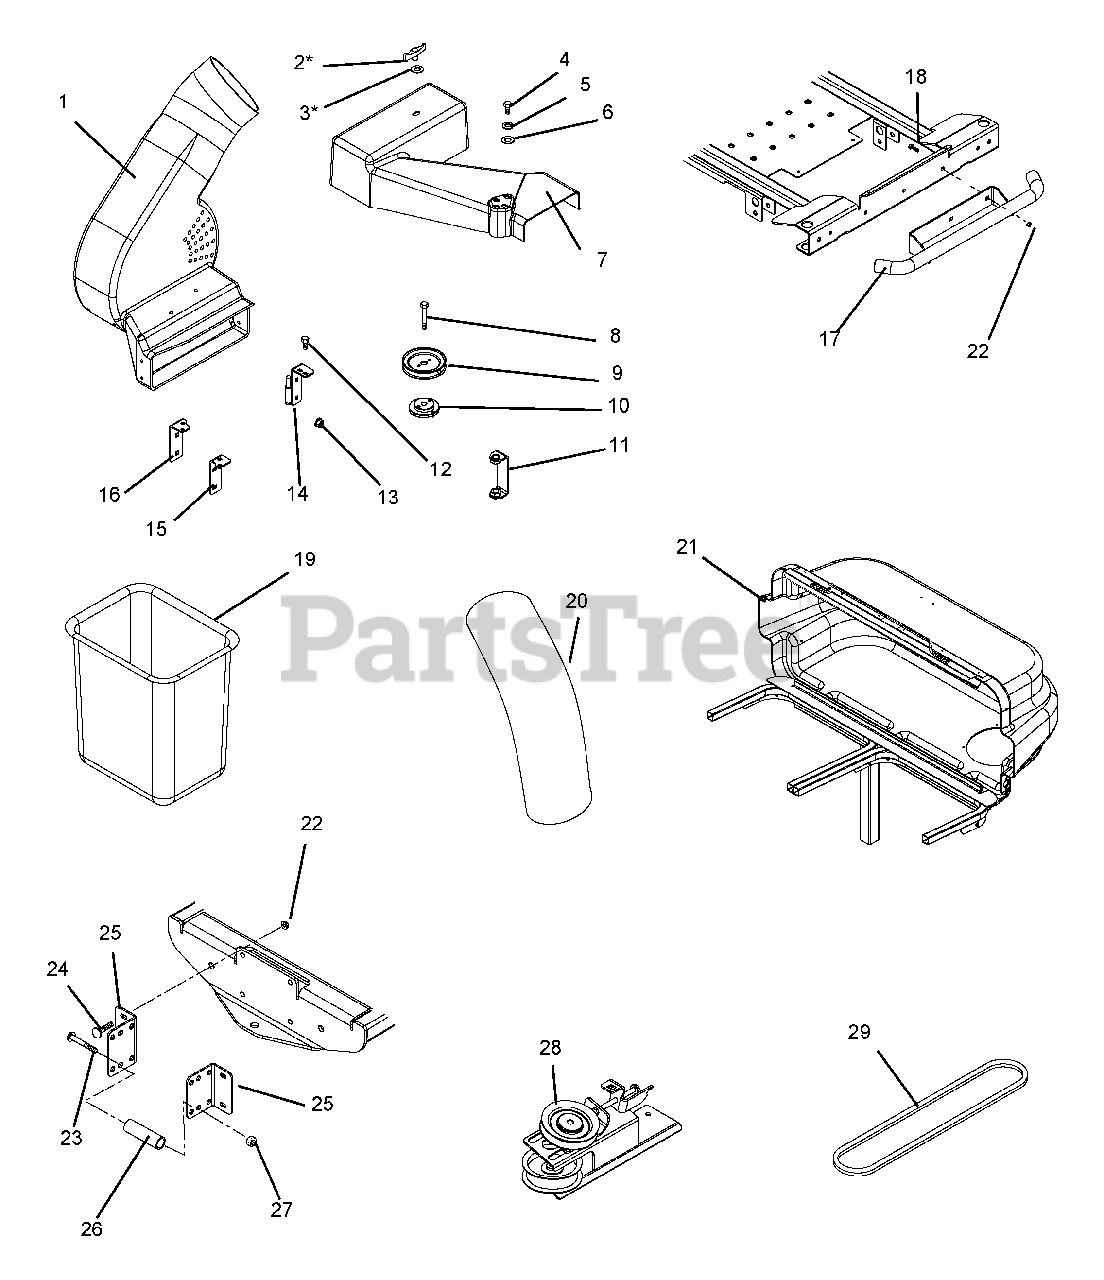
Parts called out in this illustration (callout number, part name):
1	BLOWER (SERVICE ASSEMBLY)
2	KNOB - WING .312-18 UNC
3	WSHR-FL-STL .380X1.50X.062 YWZ
4	@BLT-HEX .38-16X.75 GR5 YWZC
5	@WSHR-LK .38X.094 REG YWZC
6	@WSHR-FL-STL.438X1.00X.083 YWZ
7	BELT COVER W/DECAL
8	BLT-HEX .38-16X1.75 GR8 M-EPYZ
9	SHEAVE, 3.00 DIA.
10	ASSEMBLY, SHEAVE ADAPTER
11	SPACER, COVER
12	@BLT-HEX .25-20X.75 GR5 YWZC
13	@NUT-LK-TOP-FLG .25-20 YWZC
14	WELDMENT, REAR MOUNT BRACKET
15	BRACKET, FRONT
16	WELDMENT, FRONT MOUNT BRACKET
18	@BLT-HEX .38-16X1.00 GR5 YWZC
19	GRASS BAGGER BASKET
20	HOSE,7X38 KANAFLEX 165CL
21	Cover Assembly
22	@NUT-LK-NYL-FLG .38-16 YWZC
23	@BLT-HEX .50-13X3.00 GR5 YWZC
24	@BLT-RDHDSQNK .38-16X1.25 G5YZ
25	BKT,BAGGER MOUNT
26	SPACER, PIVOT .500X.750X1.805
27	@NUT-LK-TOP-FLG .50-13 YWZC
28	Idler Assembly
29	V-BELT, HA-WRAPPED
